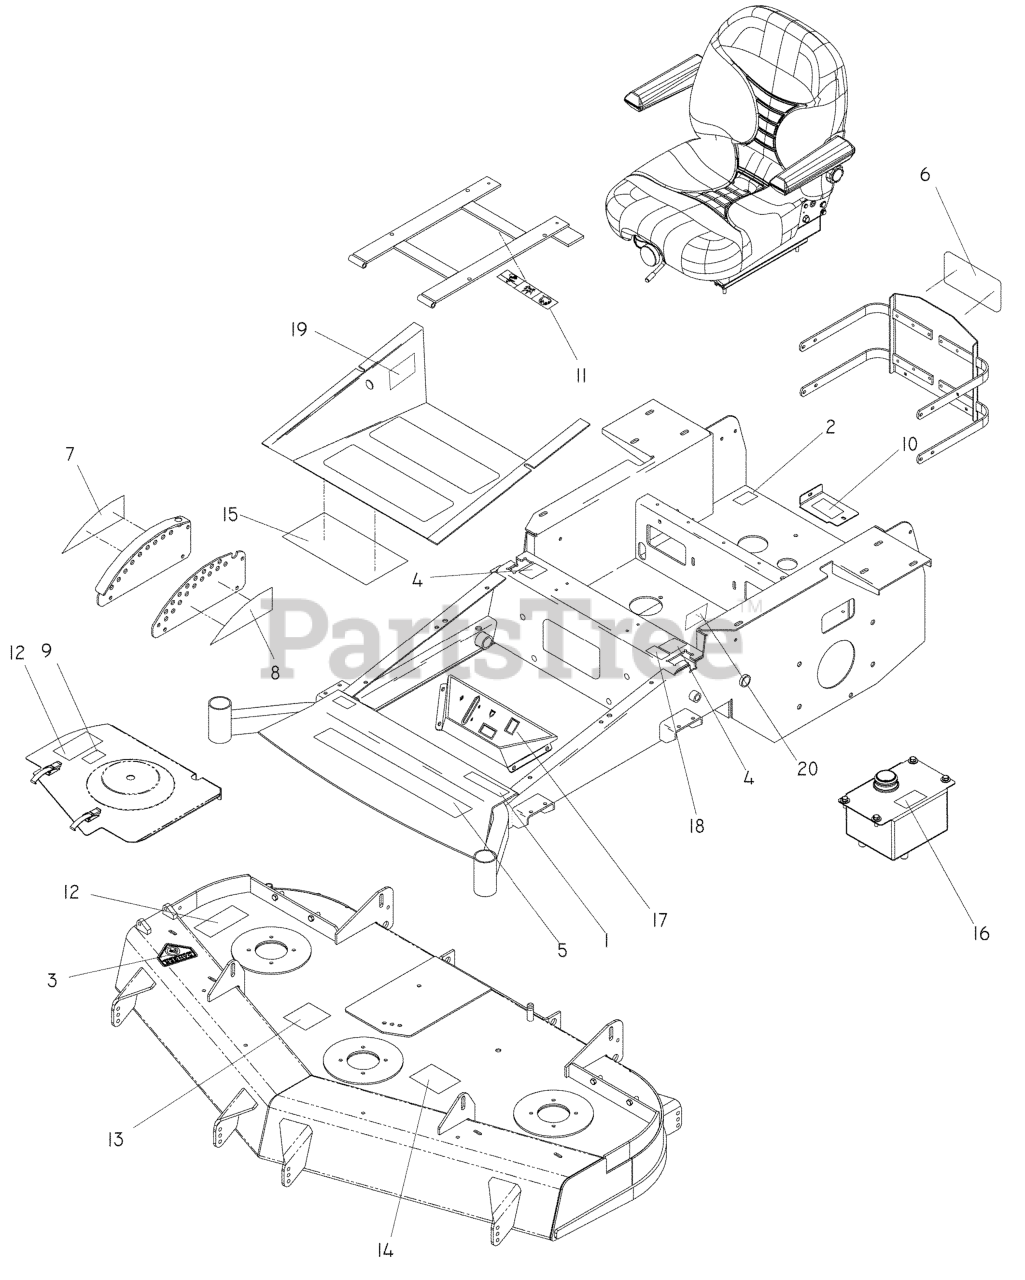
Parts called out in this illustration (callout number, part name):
1	DECAL, LZ5227
2	DECAL, PROP. 65
3	DECAL, CPSC
4	DECAL, MOTION CONTROL
5	DECAL, HUSQ 15" BLUE
6	DECAL, CROWN H 5-1/4 SILVER
7	DECAL, HEIGHT
8	DECAL, HEIGHT
9	DECAL, NO STEP
10	DECAL, BELT DRIVE
11	EURO DECAL-BATTERY WARNIN6
12	DECAL, EURO SEVERING
13	DECAL, ANTI SCALP
14	DECAL, BELT ROUTING
15	DECAL, SERVICE
16	DECAL, OIL TANK
17	DECAL, CONSOLE
18	DECAL, F.S.T.
19	DECAL, WARNING
20	DECAL, RELAYS
